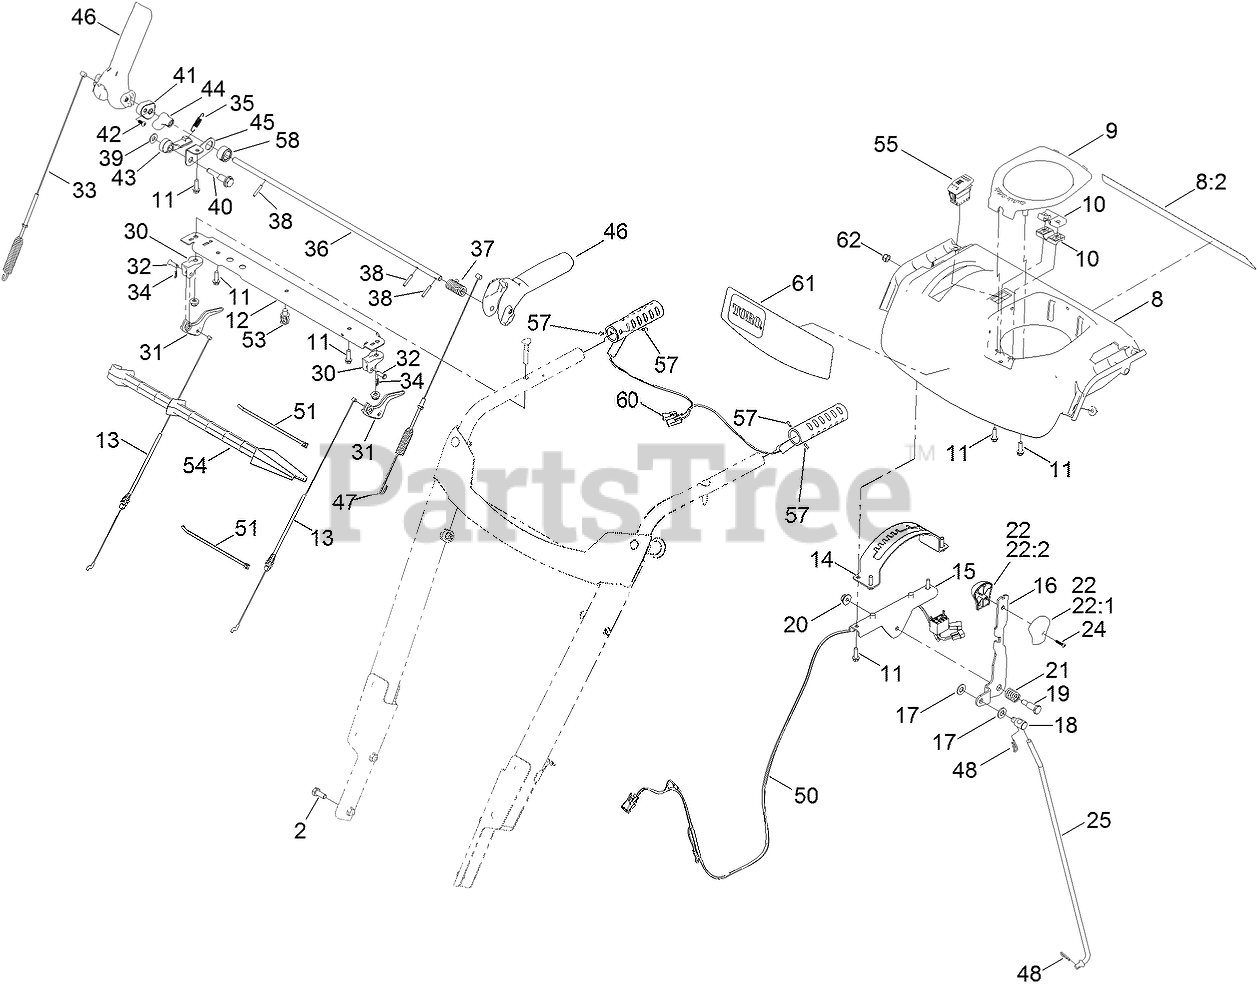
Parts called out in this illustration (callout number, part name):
2	SCREW-HH
8	PANEL-CONTROL
8:2	DECAL-SAFETY
9	COVER-QUICKSTICK
10	SUPPORT-ROD
11	SCREW-PLASTITE, HWH
12	BRACE-CONSOLE
13	CABLE-CLUTCH
14	GATE-SHIFT
15	BRACKET-SHIFT
16	SELECTOR-SPEED
17	WASHER-FLAT
18	TRUNNION-ROD
19	SCREW-SHOULDER, HH
20	NUT-HF
21	SPRING-COMPRESSION
22	SHIFT KNOB ASM
22:1	KNOB-SHIFT, LH
22:2	KNOB-SHIFT, RH
24	SCREW-PPH
25	ROD-SHIFT
30	MOUNT-LEVER, CLUTCH
31	LEVER-CLUTCH
32	PIN-CLEVIS
33	CABLE-AUGER
34	PIN-HAIR
35	SPRING-LOCKOUT, HANDLE
36	ROD-LOCKOUT
37	SPRING-TORSION, HANDLE RETURN
38	PIN-SPRING
39	WASHER-FLAT
40	SCREW-SHOULDER
41	LOCK-HANDLE
42	SCREW-PPH
43	LATCH-LOCKOUT
44	CAM-LOCKOUT
45	LINK-LOCKOUT
46	LEVER-CONTROL
47	CABLE-TRACTION
48	PIN-HAIR
50	HARNESS-WIRE, LED AND HAND WARMERS
51	TIE-CABLE
53	CLIP-TIE
54	STICK-CLEANOUT
55	SWITCH-ROCKER, ON-NONE-OFF (HEATER)
57	RIVET-POP
58	COLLAR-CAM
60	GRIP-HEATED
61	DECAL-CONSOLE
62	NUT-HEX
